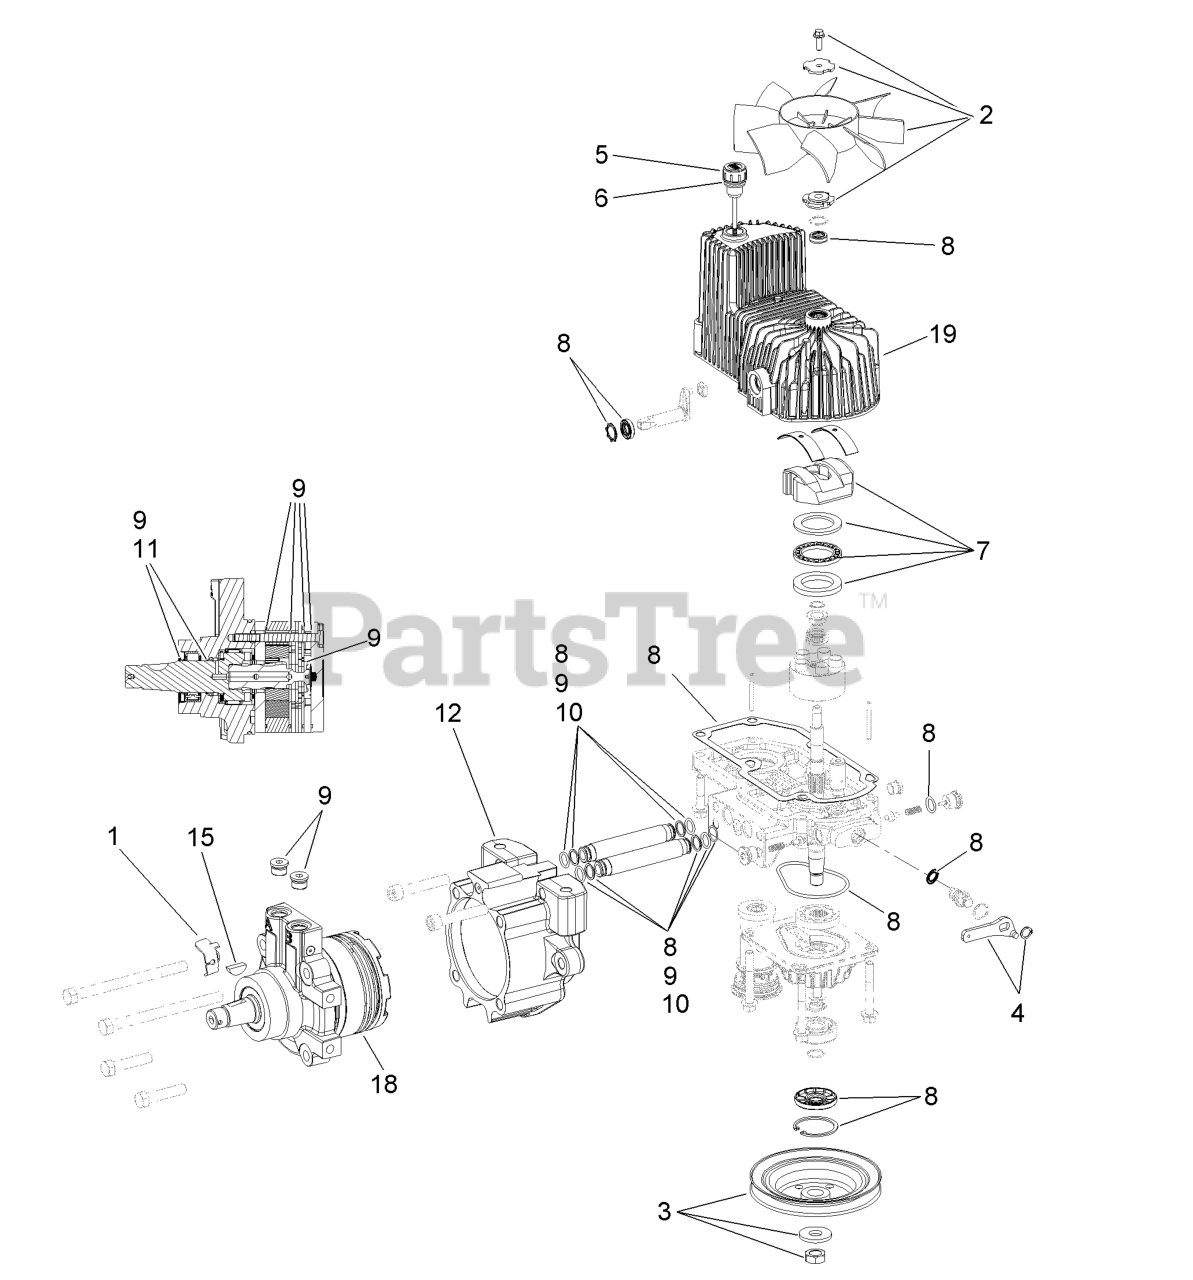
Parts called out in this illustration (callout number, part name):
1	BRACKET-ANCHOR, CABLE
2	FAN KIT
3	PULLEY KIT
4	HANDLE-BYPASS VALVE, HYDRO
5	DIPSTICK-HYDRO W/GASKET
6	GASKET-DIPSTICK, HYDRO
7	SWASH BLOCK KIT
8	PUMP SEAL KIT
9	MOTOR SEAL KIT
10	TUBE SEAL KIT
11	OUTPUT SHAFT SEAL KIT
15	KEY-WOODRUFF
19	HOUSING-HYDRO, LH
